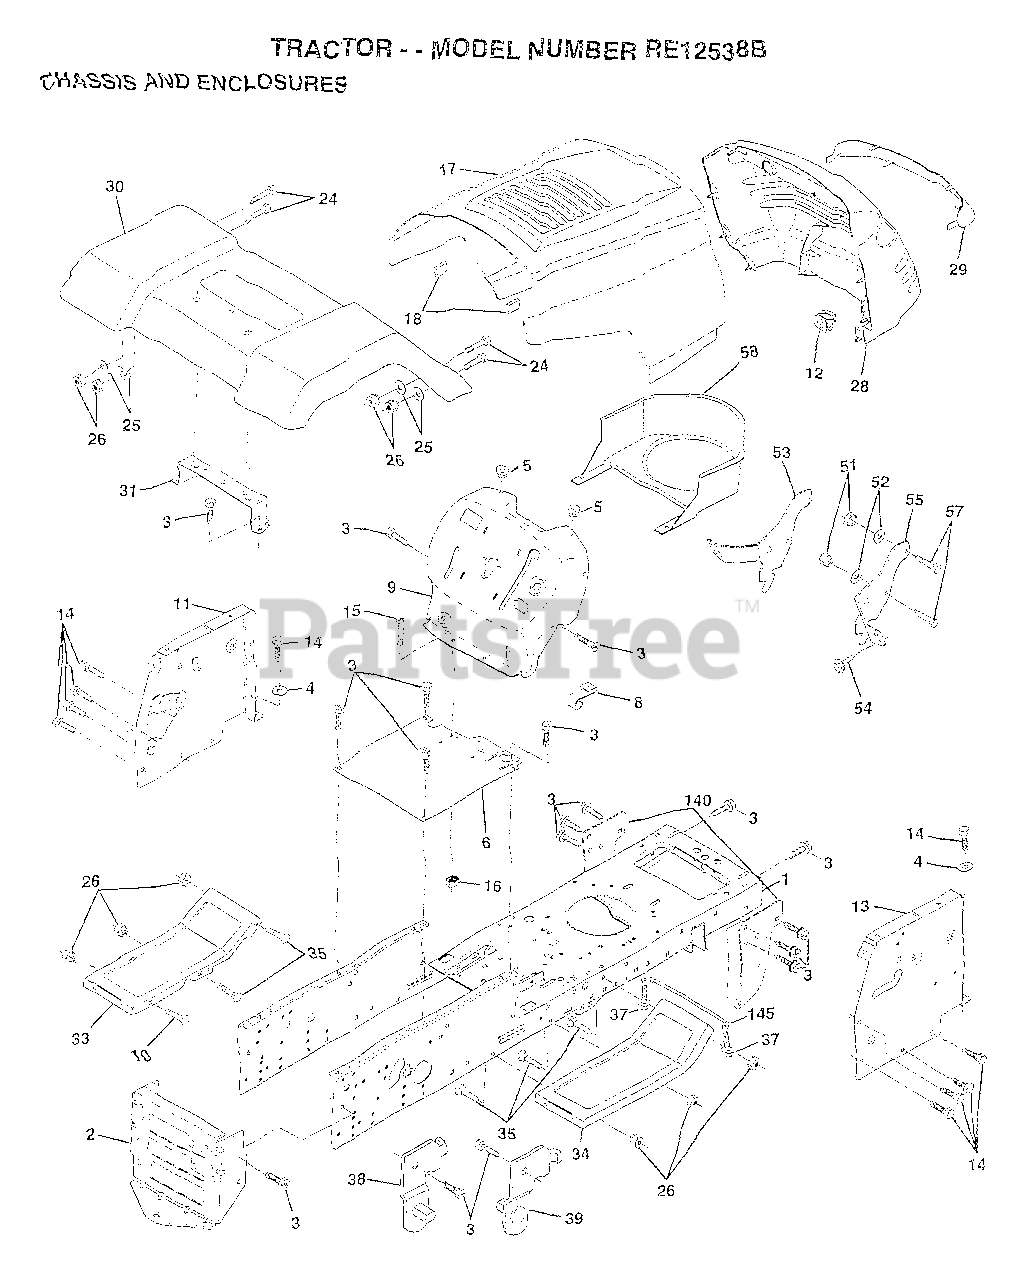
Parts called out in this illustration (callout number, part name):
3	SCREW
4	WASHER
5	BUMPER-HOOD/DASH
6	SADDLE
8	CLIP.RETAINER
9	DASH SILKSCREEN
11	"PANEL-DASH,LH"
12	CLIP.TINNERMAN
14	SCREW LT
15	SCREW
17	HOOD.STEEL.ASSY
24	BOLT
25	WASHER
26	NUT
28	GRILLE-MS428
29	LENS GRILLE
30	FENDER.LT.W/SHIFT
31	BRKT FENDER
33	FOOTREST LH
34	FOOTREST RH
35	BOLT
37	SCREW LT
38	BRACKET ASM LH
39	BRACKET ASM RH
51	NUT
52	WASHER
53	BRACKET.GRILLE.LH
54	SCREW.HEX.WS.HD
55	BRACKET.GRILLE.RH
58	AIR DUCT
140	BRKT SUSPENSION
145	"ROD POVOT,CHASSIS"
